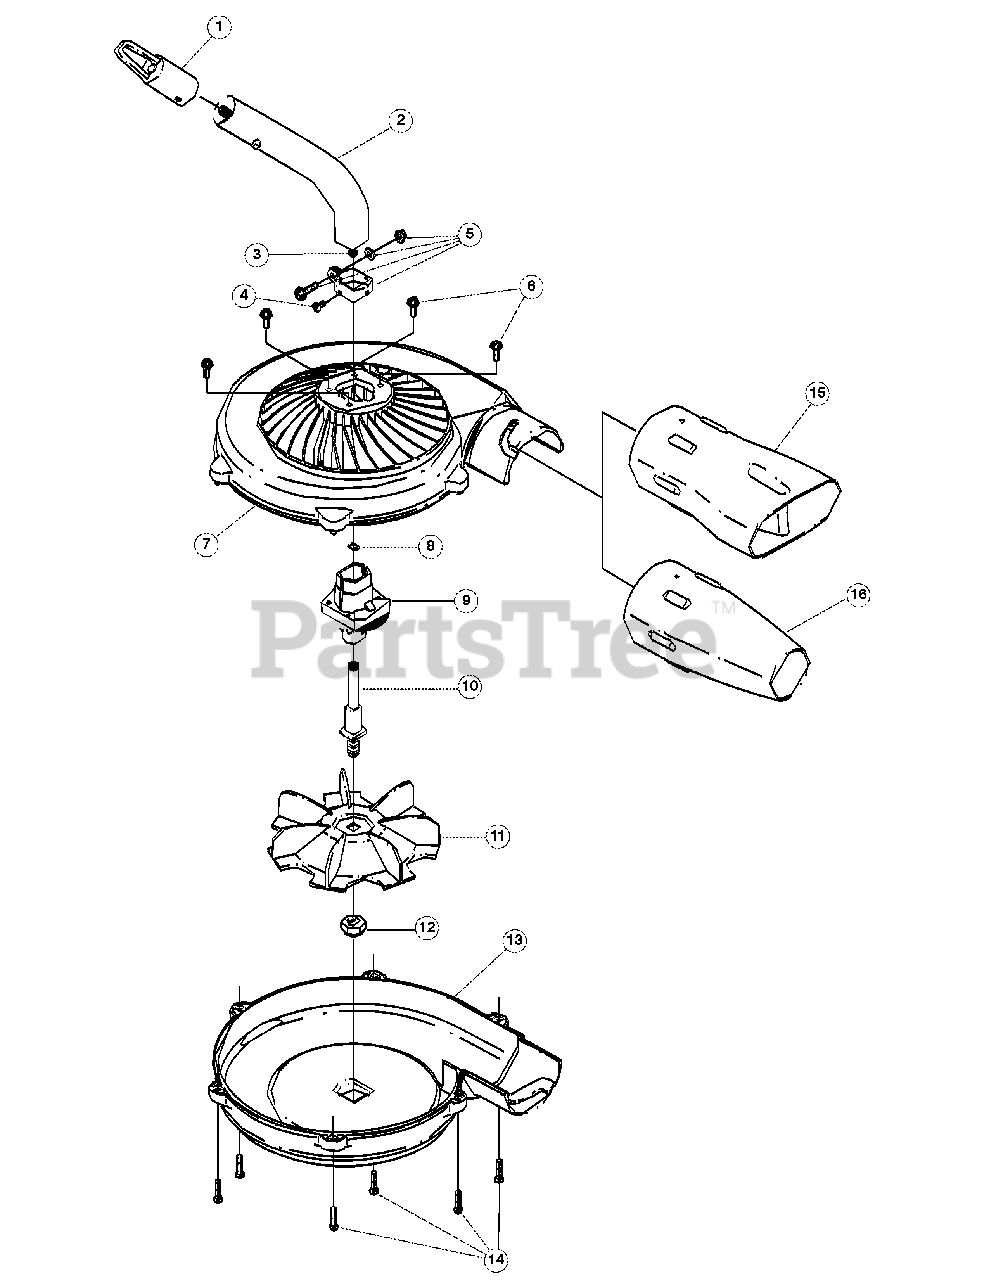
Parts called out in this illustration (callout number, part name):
1	Hanger
2	Drive Shaft Housing Assembly
3	Drive Shaft Assembly
4	Anti-Rotation Screw
5	Lower Clamp Assembly (includes 4)
6	Mounting Screw
7	Upper Housing
8	Palnut
9	Bushing Assembly Housing
10	Shaft Impeller
12	Nut and Washer
13	Lower Housing
14	Mounting Screw
15	Flare Nozzle
16	Concentrator Nozzle
